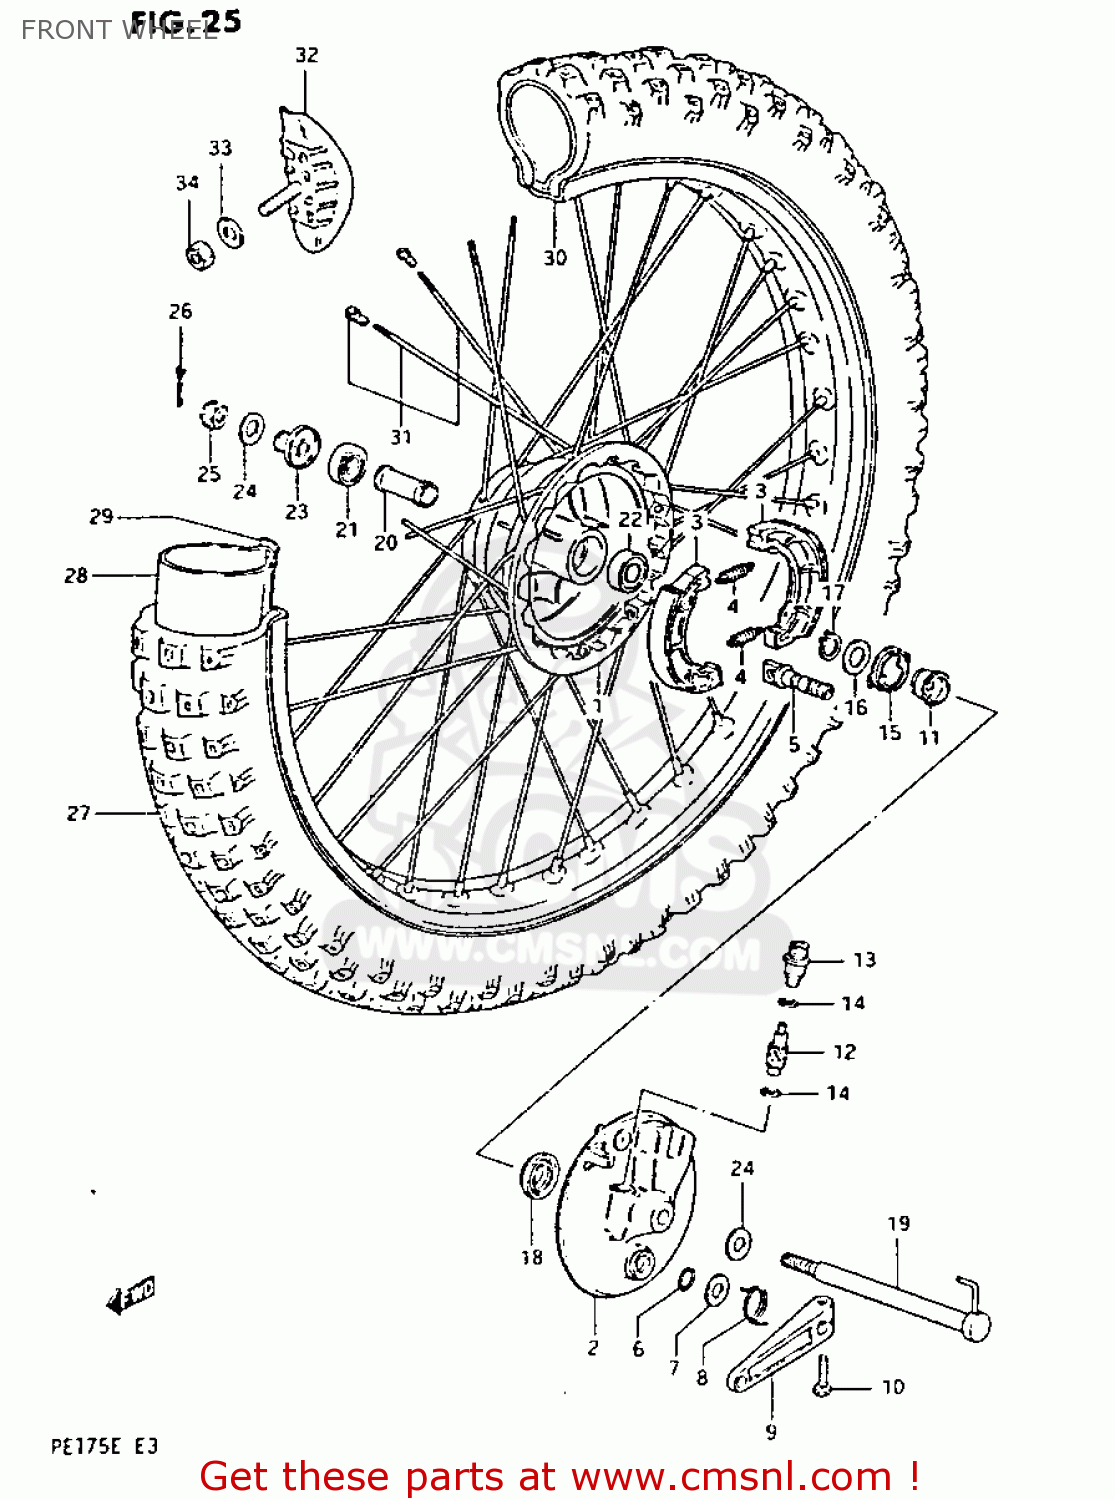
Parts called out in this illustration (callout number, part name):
1	HUB,FRONT
2	PANEL,FRONT HUB
3	SHOE,BRAKE (ASB)
4	SPRING
5	CAM,FR BRAKE
6	O RING(D:2.5,ID:11.4)
7	WASHER(12.5X20X1)
8	SPRING
9	LEVER,FRONT BRAKE CAM
10	BOLT
11	GEAR,SPEEDOMETER
12	PINION,SPEEDOMETER
13	BUSH,SPEEDOMETER PINION OUTER
14	WASHER (5.1X9X0.4)
15	DRIVER,SPEEDOMETER GEAR
16	WASHER(22.5X27X1)
17	CIRCLIP
18	SEAL,OIL(26X38X4)
19	AXLE,FRONT
20	SPACER,FRONT HUB BEARING
21	BEARING
22	BEARING
23	SPACER,FRONT AXLE,RIGHT
24	WASHER
25	NUT, REAR AXLE
26	COTTER PIN
27	TIRE,FRONT
28	TUBE
29	PROTECTOR,WHEEL,INNER
30	RIM,FRONT WHEEL (1.60X21)
31	SPOKE SET,FRONT
32	STOPPER,BEAD
33	WASHER
34	NUT
